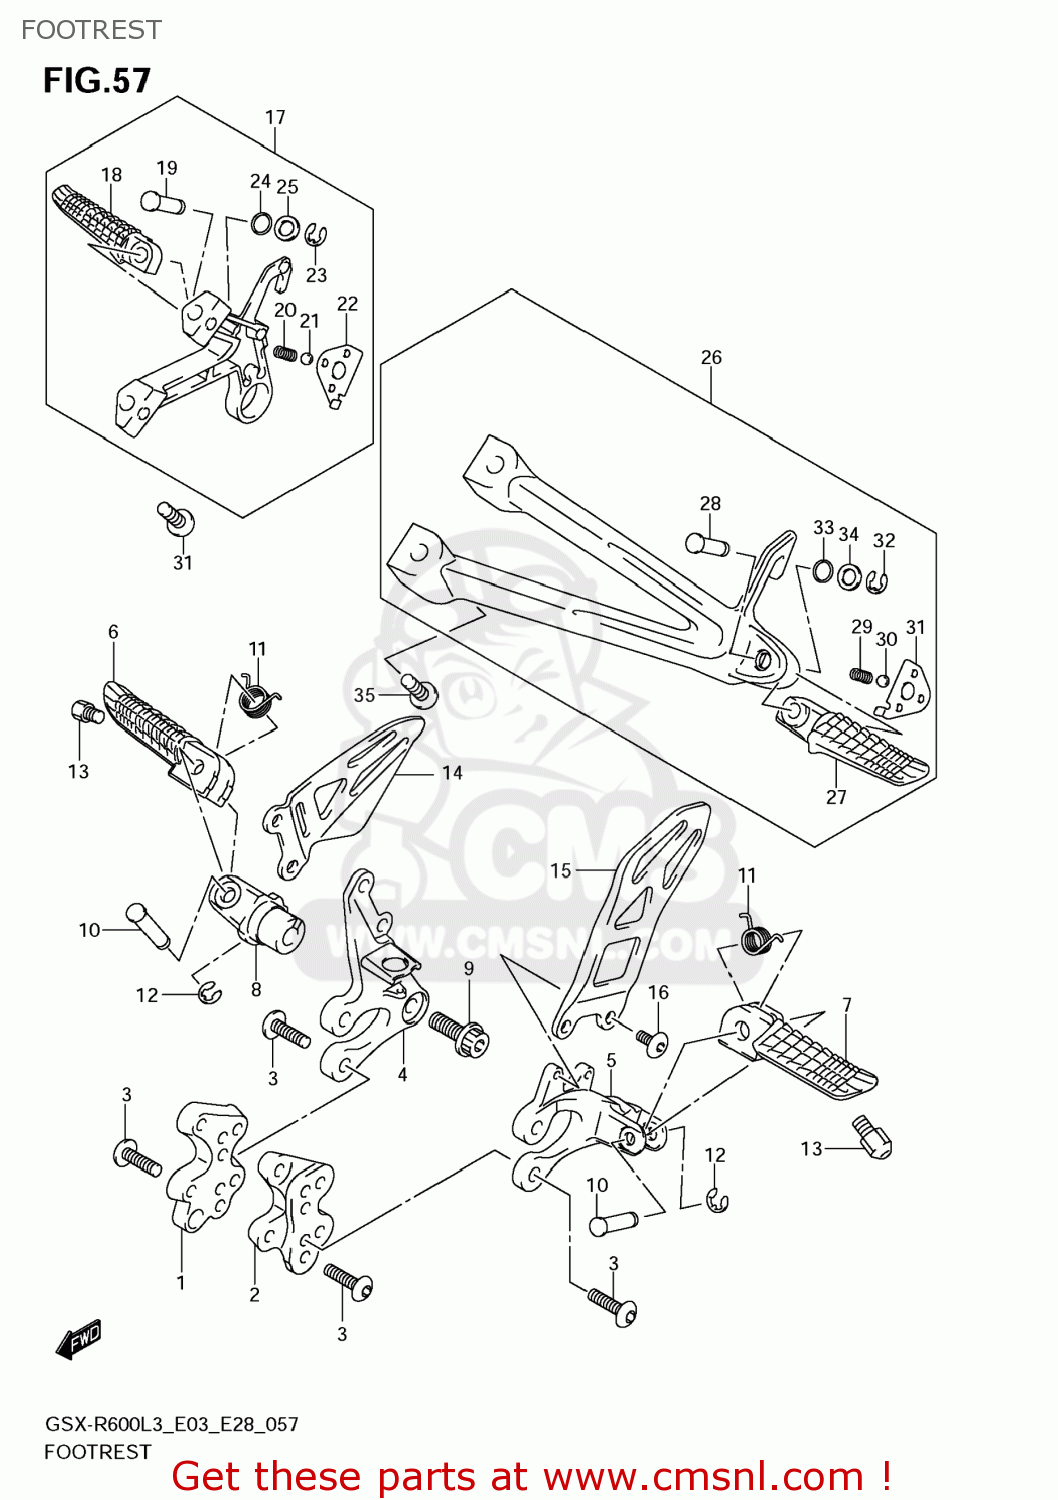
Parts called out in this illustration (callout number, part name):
1	BRACKET,FR FOOTREST NO.1,R
2	BRACKET,FR FOOTREST NO.1,L
3	BOLT(8X23)
4	BRACKET,FR FOOTREST NO.2,R
5	BRACKET,FR FOOTREST NO.2,L
6	BAR,FR FOOTREST,R
7	BAR,FR FOOTREST,L
8	HOLDER,FOOTREST
9	BOLT(10X28)
10	PIN
11	SPRING
12	E RING
13	BOLT,BANK SENSOR
14	GUARD,FR FOOTREST,R
15	GUARD,FR FOOTREST,L
16	SCREW,FOOTREST GUARD,L
17	FOOTREST ASSY,PILLION,R
18	BAR,PILLION FOOTREST,R
19	PIN
20	SPRING
21	BALL
22	PLATE,PILLION FOOTREST,R
23	E RING
24	O RING(D:2.4,ID:6.9)
25	WASHER(8.5X14X1.0)
26	FOOTREST ASSY,PILLION,L
27	BAR,PILLION FOOTREST,L
28	PIN
29	SPRING
30	BALL
31	PLATE,PILLION FOOTREST,L
32	E RING
33	O RING(D:2.4,ID:6.9)
34	WASHER(8.5X14X1.0)
35	BOLT(8X23)
